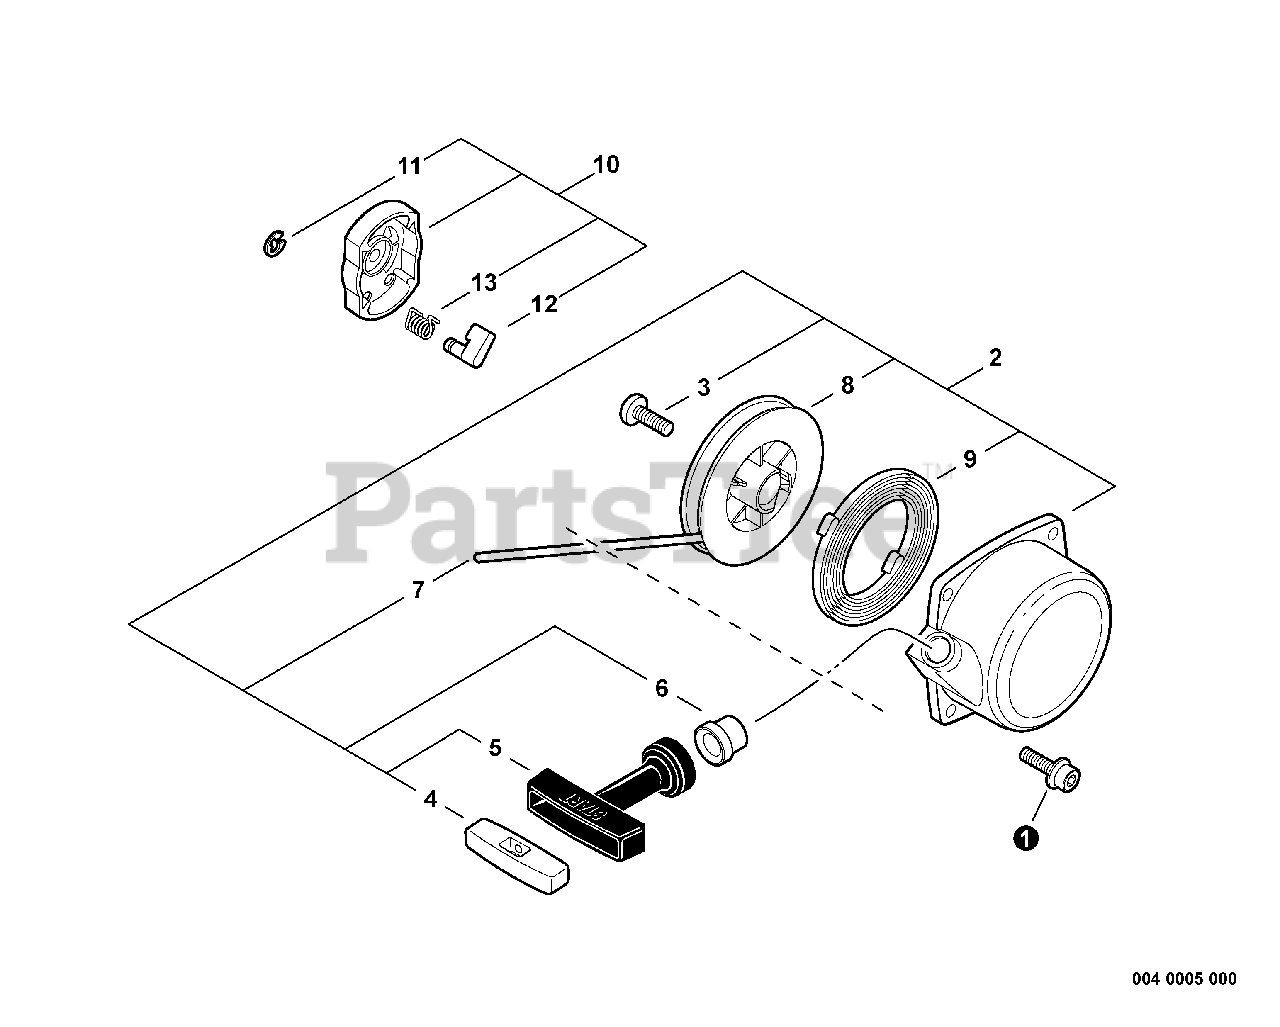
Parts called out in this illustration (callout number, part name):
1	SCREW - 5X14
2	STARTER ASSY
4	RETAINER, ROPE
5	GRIP, STARTER
6	GUIDE, ROPE
7	ROPE, STARTER - 3.5X1000
8	REEL, ROPE
9	SPRING, REWIND
10	STARTER PAWL ASSY
11	RING, RETAINING - 4
12	PAWL, STARTER
13	SPRING, RETURN
